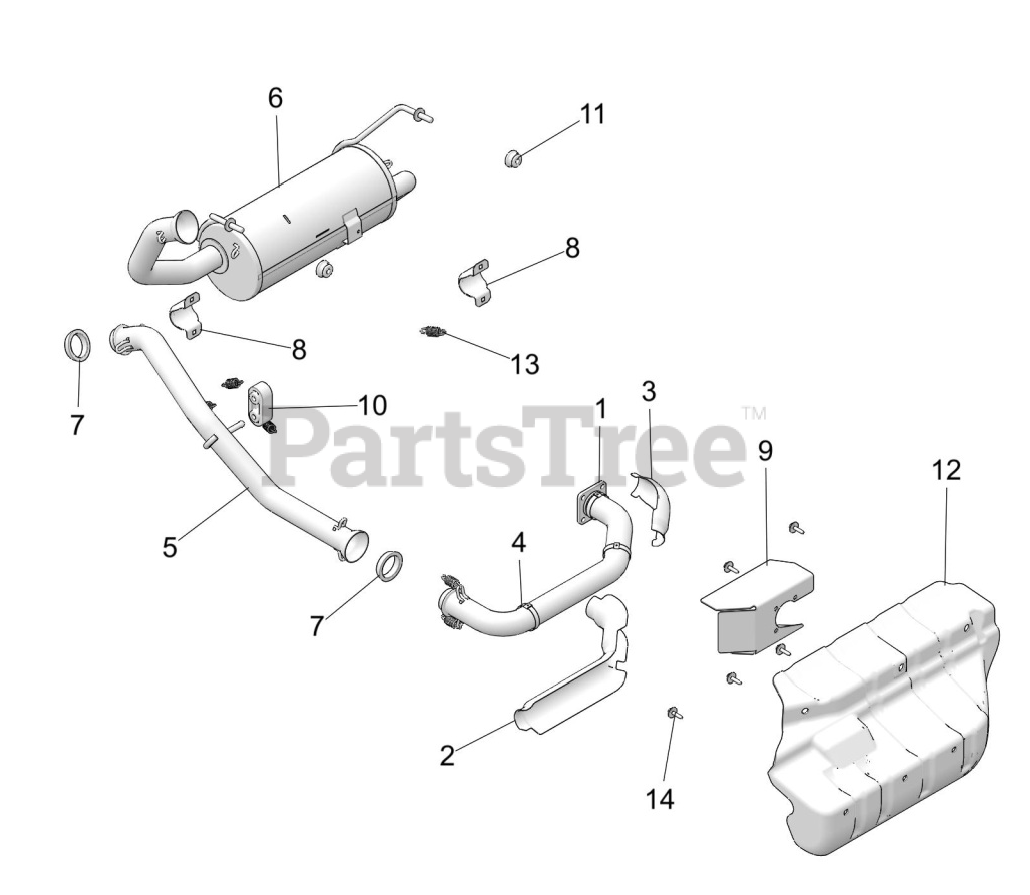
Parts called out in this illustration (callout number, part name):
1	ASM-HEADPIPE
2	SHIELD-HEAT-HEADPIPE-INNER
3	SHEILD-HEAT-HEADPIPE-FRONT-LWR
4	SHIELD-HEAT-HEADPIPE-FRONT-UPR
5	SHIELD-HEAT-SILENCER-INNER
6	WELD-SPARK ARRESTOR
7	SHIELD-HEAT-SILENCER-OUTER
8	SHIELD-HEAT,CLOSEOFF
9	ISOLATOR-EXHAUST,HANGER,HD
10	WASHER- .406X1.00X.125 FL
11	SPRING, SPHERICAL, EXHAUST
12	STUD-SPHERICAL-EXHAUST
13	SPRING-EXHAUST SS SHOTPEENED
14	SHIELD-BUSHING-SWAY BAR
15	GASKET-EXHAUST SEAL
16	ASM-SILENCER-RGR
17	GASKET-DOUBLE SPHERICAL-2"
18	SENSOR-LAMBDA-LSF 4.2
19	SCR-M8X1.25X22-HX/SO
20	SCR-HXFL-M6X1.0X25 8.8 ZPB SEM
21	SCR-HHSEMS-M6X1.0X10 A286-LOCK
22	SCR-HXFL-M6X1.0X10 8.8
